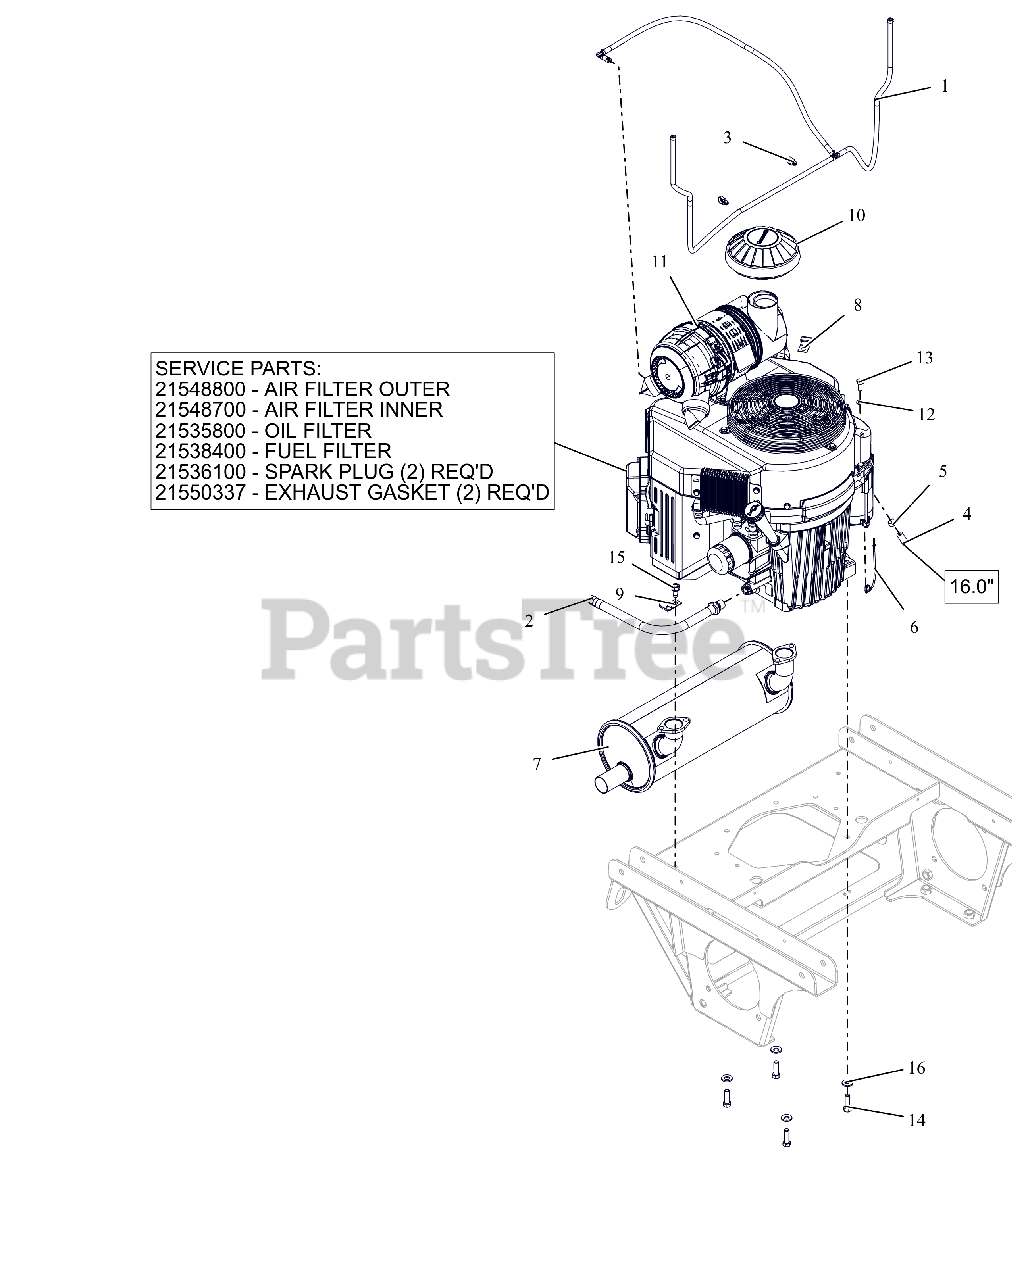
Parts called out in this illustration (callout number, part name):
1	ASM, VAPOR LINE
2	HOSE, OIL DRAIN
3	ROUTING CLIP (1/2" ID)
4	HOSE, .25 LOW-PERM BULK GAS
5	CLAMP, FUEL LINE
6	LEAD - STARTER SOLENOID
7	MUFFLER - 34HP KAWASAKI VERT.
10	CAP, AIR CLEANER INTAKE (2")
11	ENGINE - KAWASAKI FX1000
11	FILTER, OUTER
11	FILTER, INNER - KAW
11	FILTER,OIL - KAW
11	FUEL FILTER - KAWASAKI
11	PLUG, SPARK
11	GASKET, EXHAUST (11061-7061)
12	WSHR,LK-REG .312X.078 ZCC
13	BLT, HEX M8-1.25X20 G8.8 ZCC
14	BLT, HEX .38-16X1.25 G5 ZCC NT
15	SCR,TAP .375-16X.75 HWH TR ZCC
16	WASHER, 3/8" SPRING DISC
